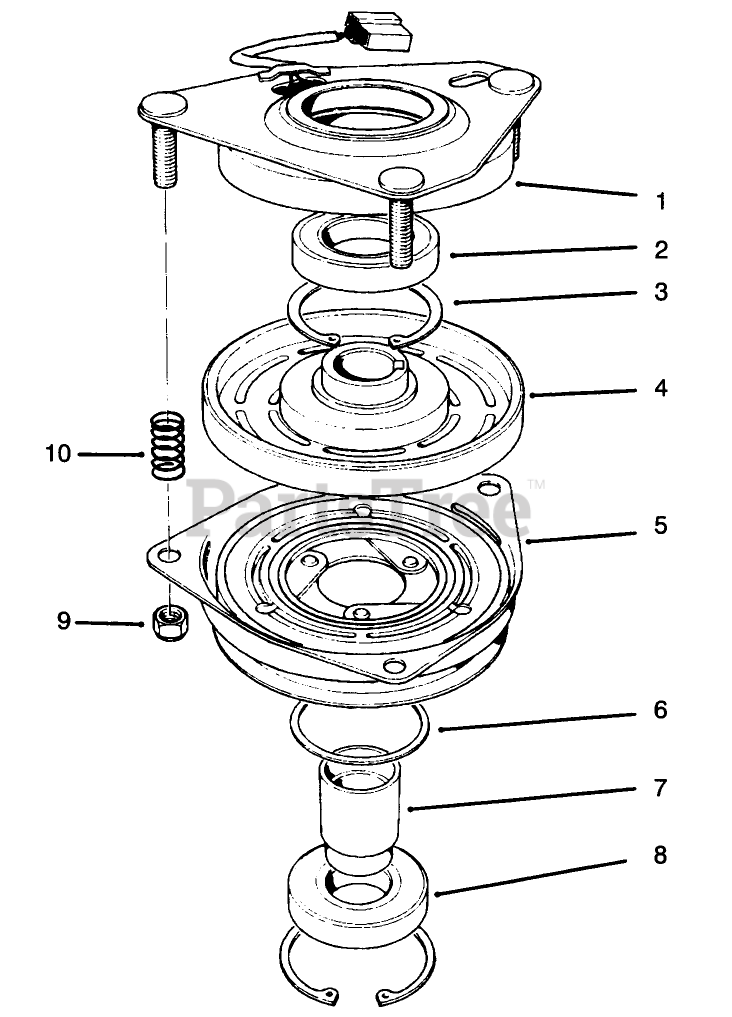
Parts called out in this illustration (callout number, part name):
1	FIELD BEARING ASM
2	BEARING-FIELD
3	RING-RETAINING
4	FIELD COIL/ROTOR BEARING ASM
6	SPACER-BEARING, PULLEY
7	COLLAR-BEARING
9	NUT-HEX
10	SPRING
